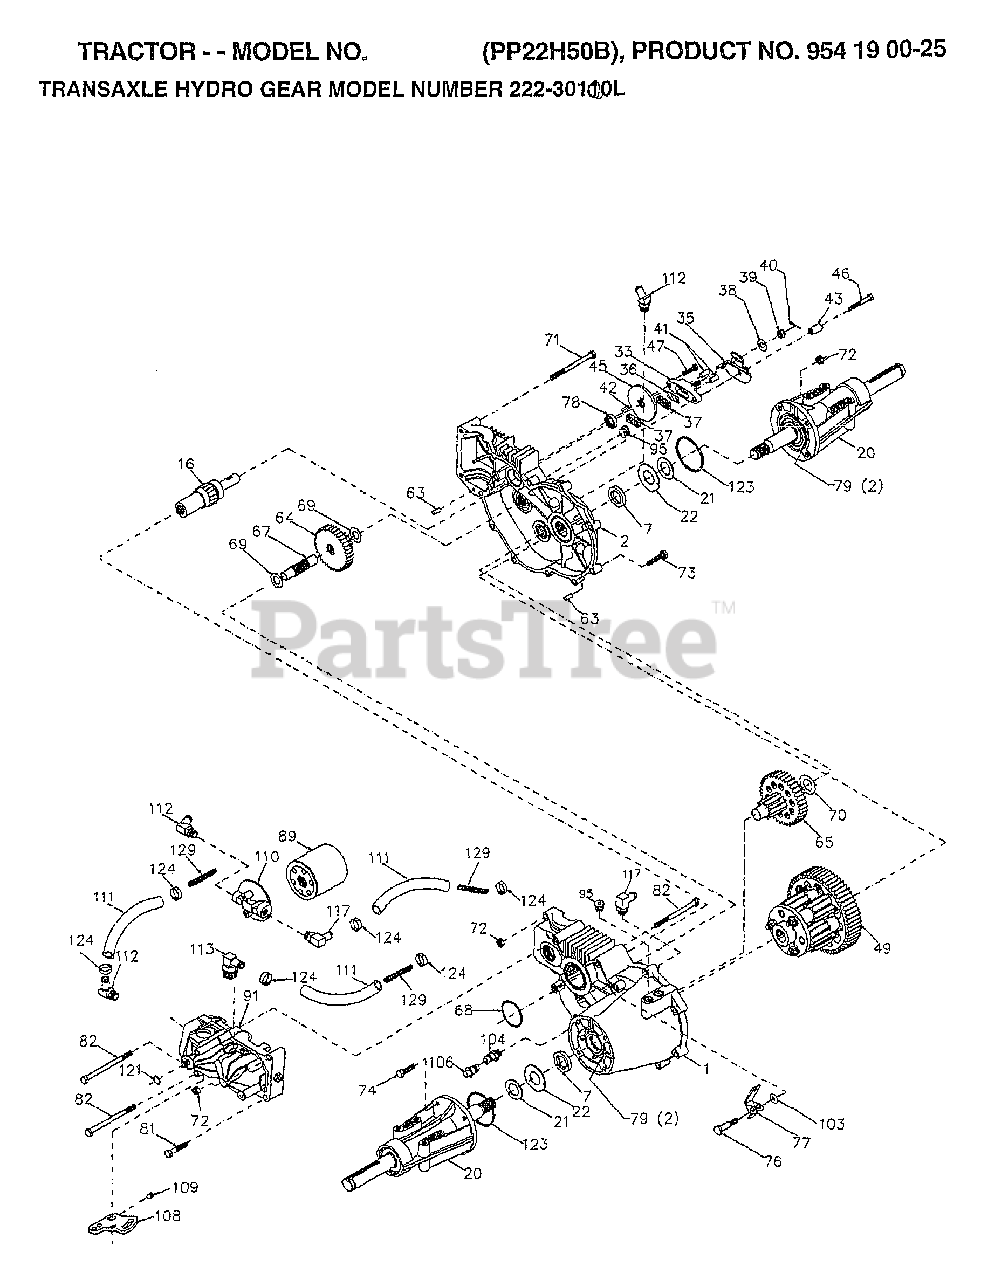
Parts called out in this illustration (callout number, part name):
1	HOUSING LH 70086
2	HOUSING RH 70088
7	SEAL.OIL.44782.HY
16	SHAFT BRAKE 62877
20	AXLE MTG 70087
21	WASHER 44805
22	WASHER 44806
33	YOKE.BRAKE.62589
35	ARM BRAKE 50214
36	PUCK PLATE 44134
37	PUCK BRAKE 44132
38	WASHER HYD 44130
41	PIN BRAKE 44127
42	KEY HI PRO 44143
43	SPACER 50259
45	DISC BRAKE 44090
46	BOLT 1/4-20 44276
47	BOLT 1/4-20 44433
49	DIFFRENTIAL.70251
63	PIN DOWL 44757
64	GEAR.14-38.44776
65	PINION DRIV 70051
67	SHAFT-44779
68	O RING 44781
69	WASHER 44795
70	WASHER 44794
71	BOLT 5/16 44827
72	LOCKNUT.43064
73	BOLT 5/16 44841
74	SCREW 5/16 45089
76	BOLT SHOULD 44785
77	ARM FREEWHL 44786
78	SEAL.OIL.44761
81	BOLT 5/16 43084
82	BOLT 5/16 44820
89	FILTER SPIN 50037
91	PUMP.BDU-10L-122
95	PLUG.9005110-5600
96	FITTING.SAE.50257
103	WASHER.50169
104	CAP.VENT.70109
106	O-RING.ASM.70110
108	ARM.CONTROL.45007
109	SCREW.SET.50018.
110	FILTER.HEAD.50207
111	HOSE.50632
112	FITTING.SAE.50604
113	FITTING.SAE.50592
117	FITTING.SAE.50589
123	O-RING.50405
124	CLAMP.50590
129	SPRING.LONG.50667
